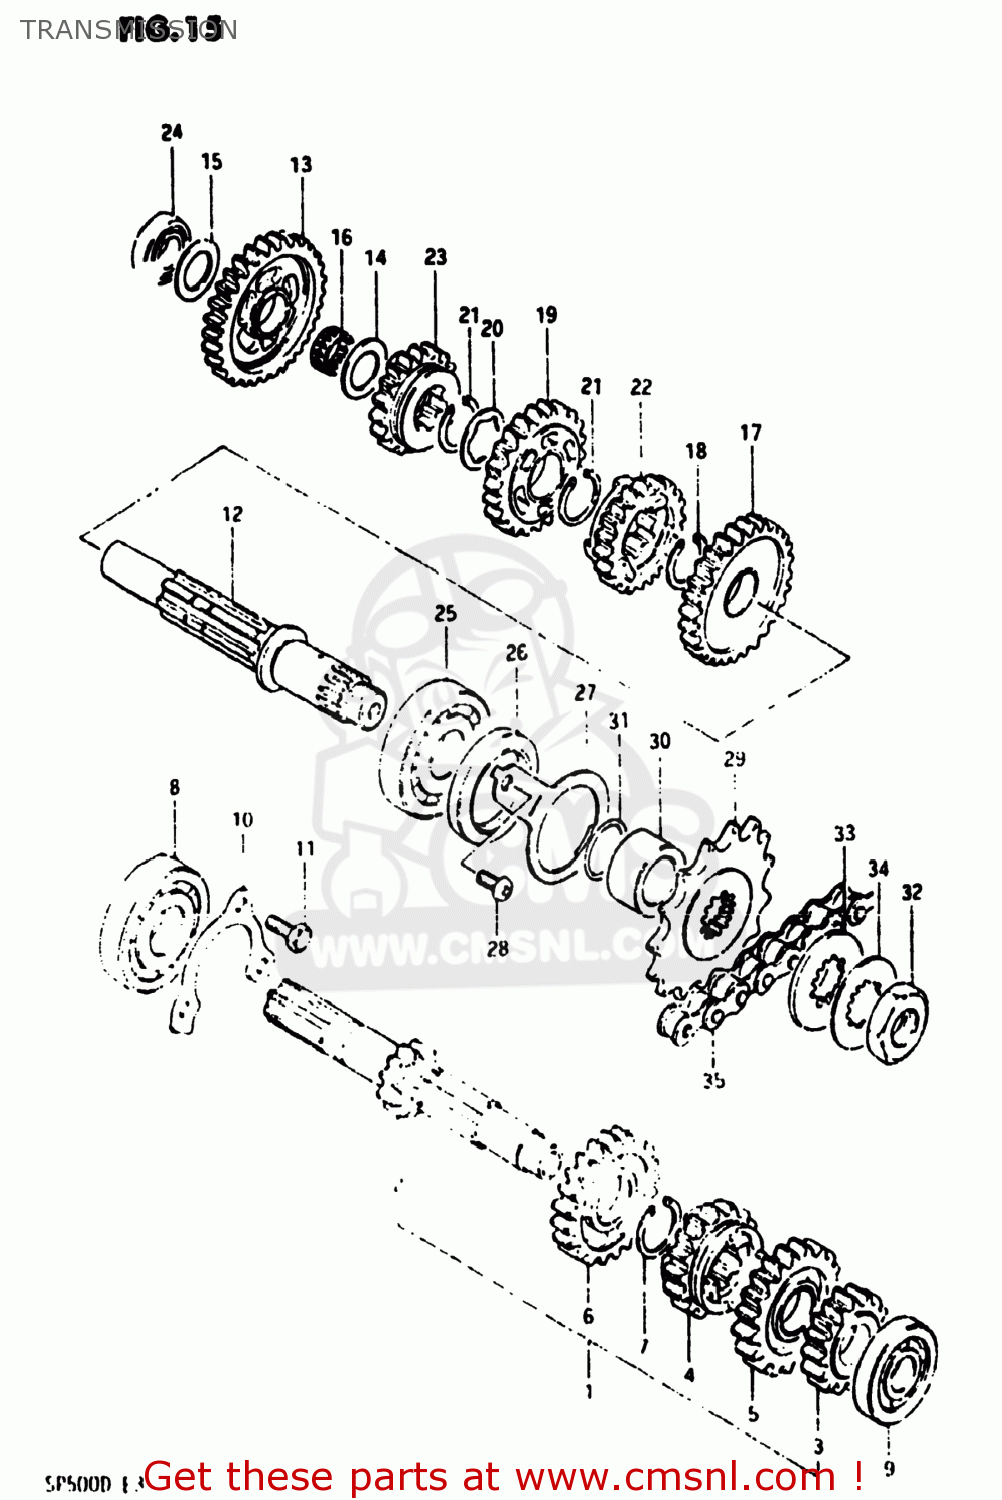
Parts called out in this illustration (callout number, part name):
1	SHAFT,COUNTER
2	SHAFT,COUNTER
3	GEAR,SECOND DRIVE
4	GEAR,THIRD DRIVE
5	GEAR,FOURTH DRIVE
6	GEAR,FIFTH DRIVE
7	CIRCLIP
8	BEARING
9	BEARING
10	PLATE,COUNTERSHAFT BEARING
11	BOLT
12	SHAFT,DRIVE
13	GEAR,FIRST DRIVEN
14	WASHER
15	WASHER
16	BEARING(20X24X10).8
17	GEAR,SECOND DRIVEN
18	CIRCLIP
19	GEAR,THIRD DRIVEN
20	WASHER,LOCK
21	CIRCLIP
22	GEAR,FOURTH DRIVEN
23	GEAR,FIFTH DRIVEN
24	BEARING(20X42X12)
25	BEARING
26	SEAL,OIL(32X42X7)
27	PLATE,DRIVESHAFT OIL
28	BOLT
29	SPROCKET,ENGINE(NT:15)
30	SPACER (22X32X13.4)
31	O RING(D:1.7,ID:22)
32	NUT
33	SPACER,ENGINE SPROCKET
34	WASHER,LOCK
35	CHAIN ASSEMBLY,DRIVE
